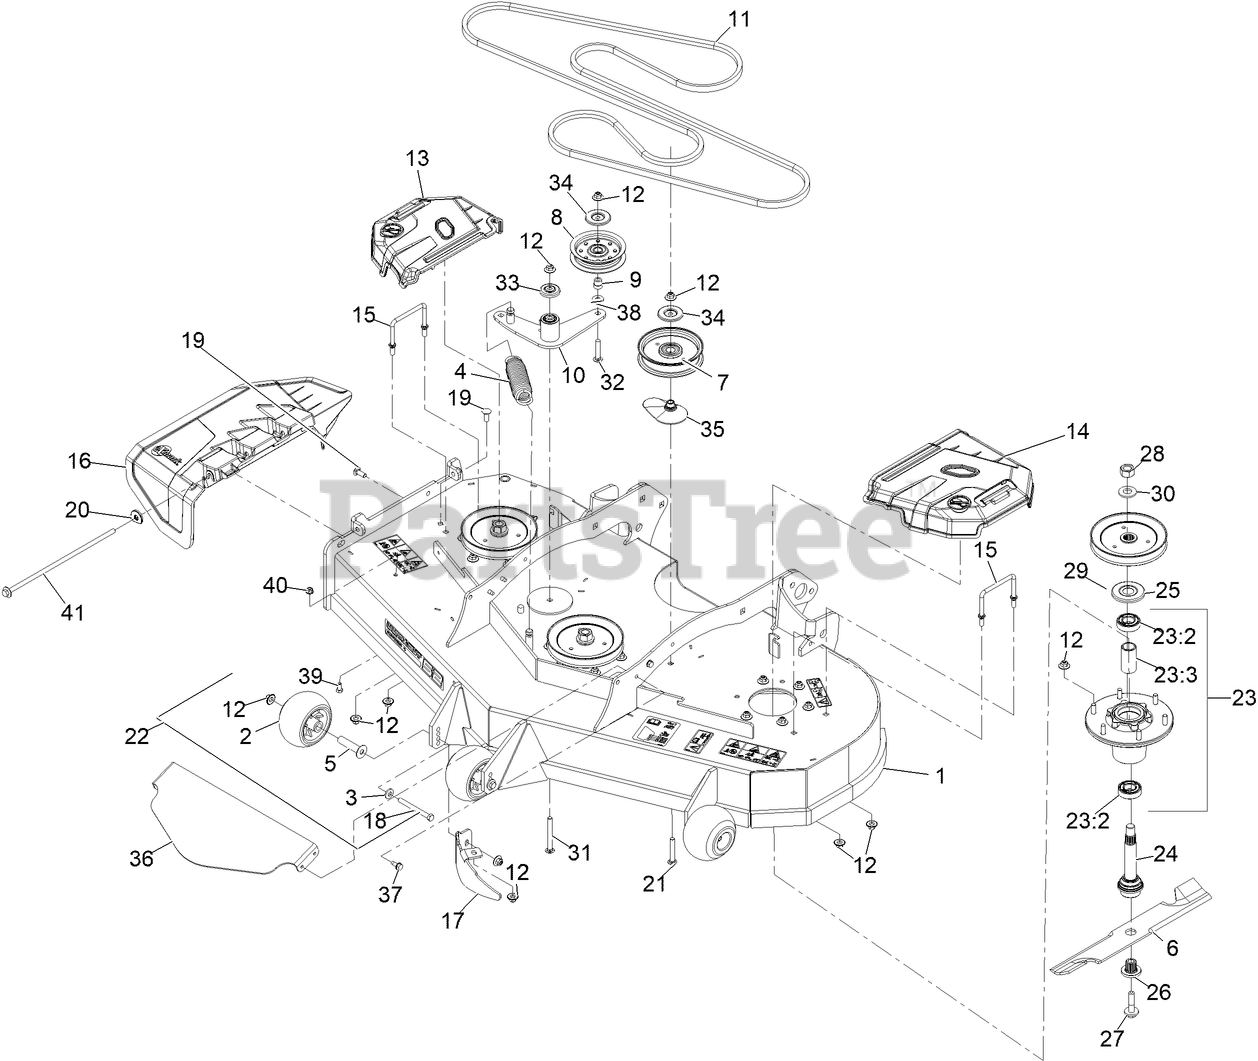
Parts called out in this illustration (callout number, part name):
1	ASM-DECK W/DECALS 524
2	ROLLER-SCALP, ANTI
3	WASHER-BELLEVILLE
4	SPRING-EXTENSION
5	AXLE, ROLLER
7	Pulley-Idler, Flat
9	BUSHING,IDLER
10	IDLER ARM ASM W/BEARINGS
12	Nut-Nyloc 3/8-16 Flg
13	SHIELD, RT
14	SHIELD, LT
15	WIREFORM-COVER
16	Chute-Deck Discharge
17	BAFFLE-DOGLEG, LZ-VT52
18	SCREW-HH 3/8-16 X 3 3/4 GR 8
19	SCREW-CARR
20	Retainer, Chute
21	SCREW-CARR
22	KIT, ANTI-SCALP ROLLER
23	ASM-CUTTER HSG WITH BEARINGS
23:2	BEARING-BALL
23:3	SPACER-BEARING
24	ASM-SPINDLE AND SEAL
25	GUARD-BEARING, TOP
26	BUSHING,SPLINED
27	SCREW,SEMS 1/2-20 X 2.19
28	NUT-HEX
29	SHEAVE,BLADE DRIVE 6.50
31	SCREW-CARR
32	SCREW-CARR
33	GUARD-TOP
34	SHIELD-DUST
35	SPACER-PULLEY
36	Guard-Front Deck
37	SCREW-THD ROLL, HWH
38	WASHER-FLAT
39	SCREW-HH
40	NUT-HF, NI
41	Pin, Chute
